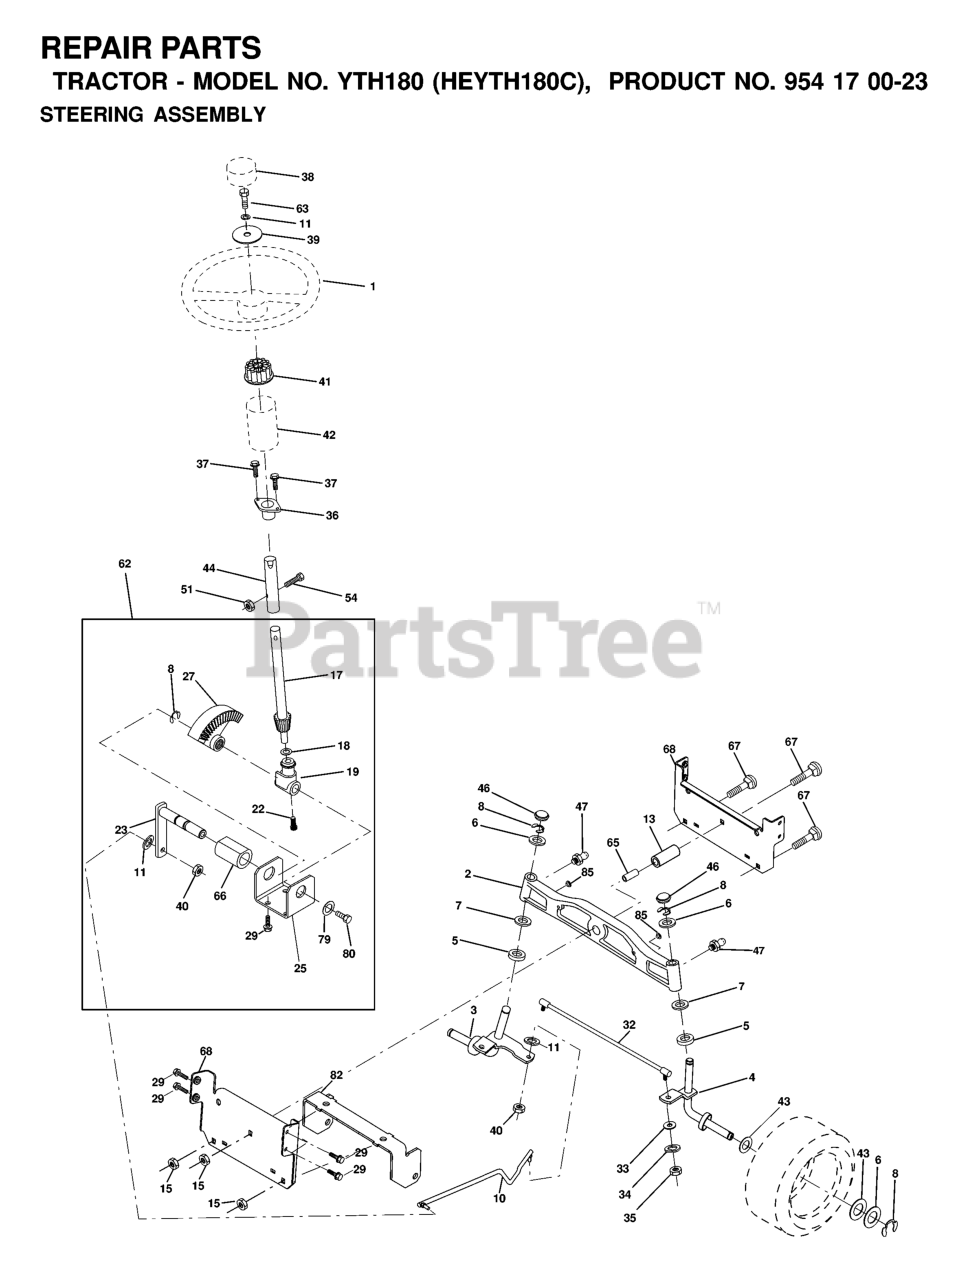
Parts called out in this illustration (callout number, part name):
1	STEERING WHEEL
2	AXLE
3	SPINDLE.ASM.LH.15"TIRES
4	SPINDLE.ASM.RH.15"TIRES
5	THRUST WASHER
10	DRAGLINK.15".TIRES
11	WASHER, LOCK 3/8
13	TUBE, PIVOT AXLE
15	NUT
17	SHAFT ASM STEERING
18	THRUST WASHER
19	STEERING SHAFT SUPPORT
22	SCREW.HX.WSH.HD
23	SHAFT ASSY PITTMAN
25	BRACKET STEERING
27	GEAR.SECTOR
29	SCREW 3/8-16X3/4
32	TIE ROD
33	WASHER M
34	WASHER.LOCK.HVY.HLCL.SPR.5/16
35	LOCKNUT
36	BUSHING, STEERING
37	SCREW.TT.#10-32X.5.3/8.FLANGE
38	CAP.WHEEL.STEERING.GREY
39	Washer 13/32 x 1-1/20 x 11 Gauge
40	GRIPCO NUT
41	STEERING WHEEL ADAPTOR
42	BOOT STEERING
44	EXT SHAFT STEERING
46	CAP.SPINDLE.BLACK
47	ZERK M
51	NUT.71038.31-18.HEX.NYLOCK
54	BOLT.5/16-18X1-1/4 FULL.THREAD
62	STEERING KIT
65	SPACER BRACE AXLE
66	BEARING ARM
67	BOLT CARRIAGE
68	BRACE.AXLE.15"TIRES
74	JOINT
76	TIE ROD
79	WASHER
80	BOLT.HX.NYLON3/8-16X
82	BRACKET
85	FASTENER.XMAS.TREE
